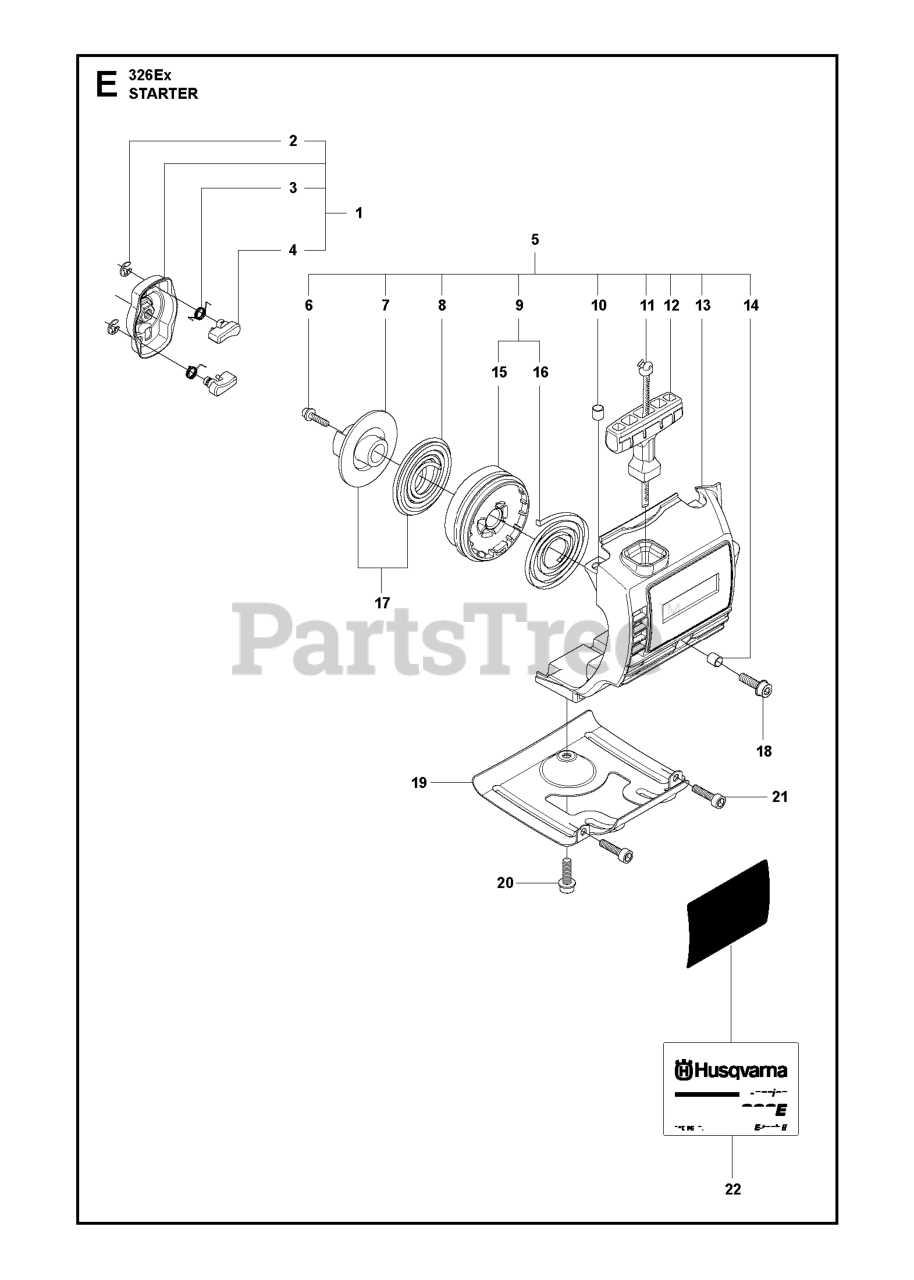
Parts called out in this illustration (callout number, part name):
1	STARTER PAWL BRIDGE
4	STARTER PAWL
5	RP STARTER ASSY
7	DRIVER PULLEY
8	SPRING - DRIVER
9	STARTER PULLEY
10	SPACING SLEEVE
11	STARTER ROPE
12	STARTER HANDLE
13	RP STARTER HOUSING
14	SPACING SLEEVE
15	STARTER PULLEY
18	SCREW
20	SCREW
